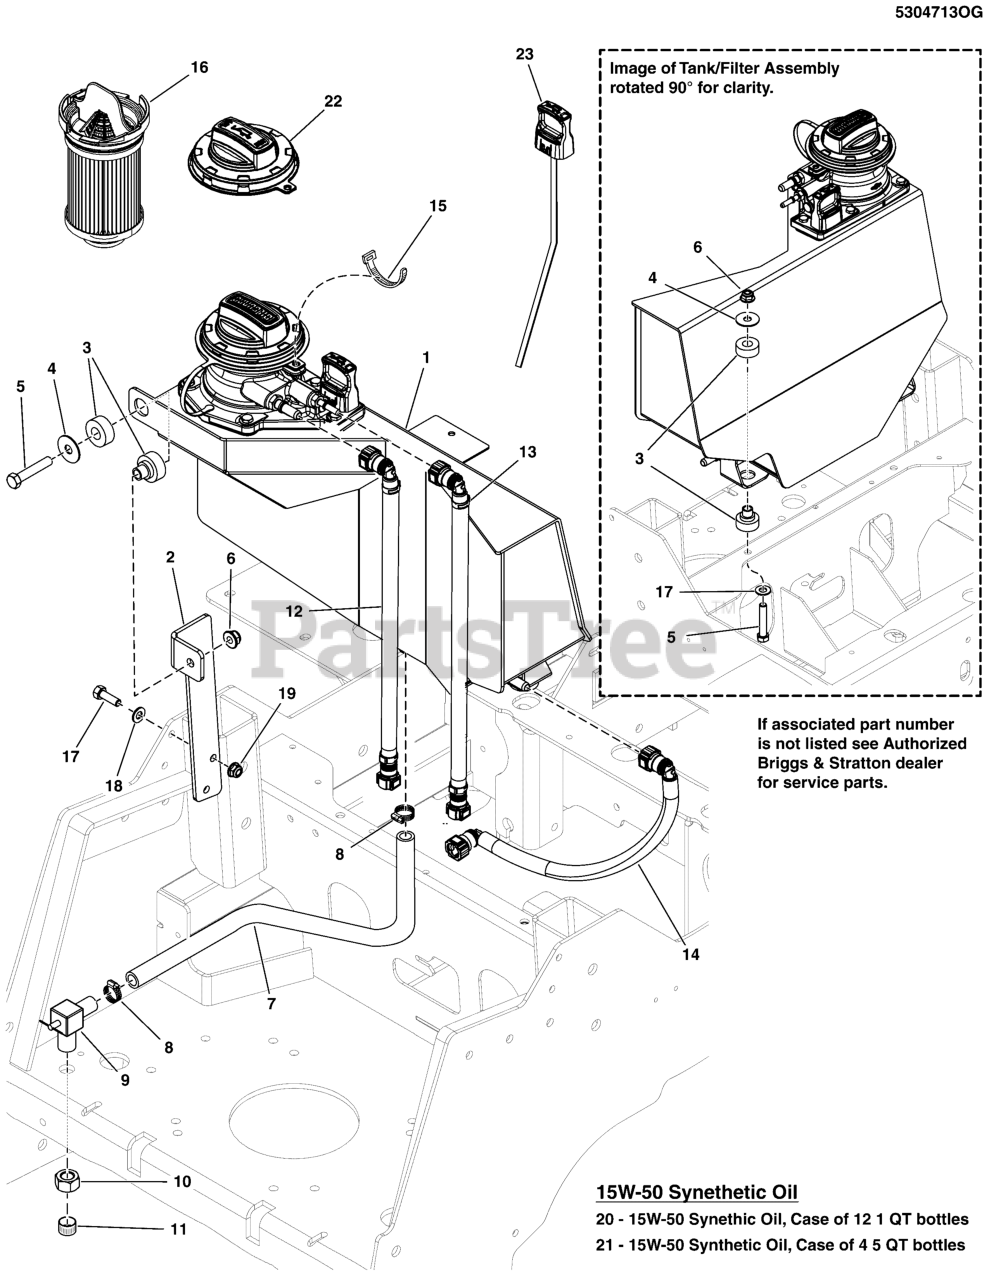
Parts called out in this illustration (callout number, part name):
1	TANK, Oil
1	TANK, OIL
2	MOUNT, TANK TOP, 2100 - BLK
3	MOUNT, ISO, BOTTOM, RAD 5000Z-DIESEL
4	WASHER, 3/8" Fender
5	BOLT, 3/8-16 X 2, GD5, CZ
6	NUT, 3/8 - 16 HEX NYLOCK FLANGE
7	HOSE, 1/2" X 7/8" OD X 22" LONG
8	CLAMP, #6 HOSE, STAINLESS
9	VALVE, OIL DRAIN, M16X1.5 TO 1/2"
10	NUT, HEX, M16-1.5, DAPCO 4071
11	OIL DRAIN CAP, OIL GUARD, DAPCO 4692
12	HOSE, OIL SCAVENGE
13	HOSE, Oil Vent
14	HOSE, OIL SUPPLY
16	FILTER, OIL
17	BOLT, 5/16-18 X 1" GRD5 YZ
18	WASHER, 5/16" SAE
19	NUT, 5/16-18 HEX NYLOCK FLANGE NUT
20	OIL, 15W-50, SYNTHETIC, CASE X 12- 1QT
21	OIL, 15W-50, SYNTHETIC, CASE X 4- 5QT
22	CAP, Oil Fill
23	DIPSTICK
